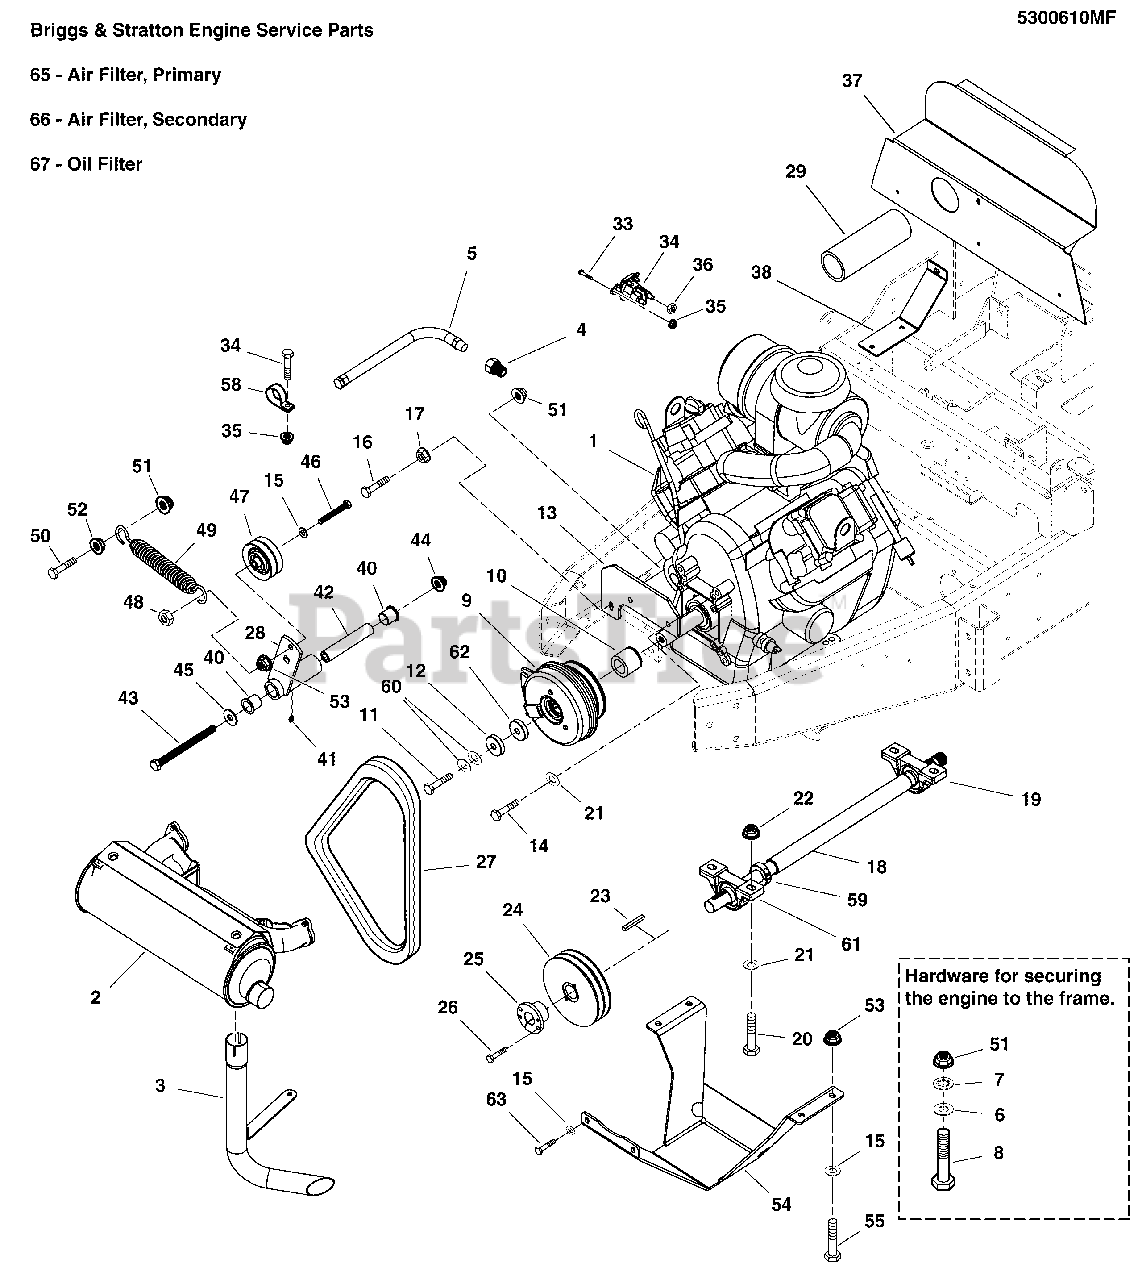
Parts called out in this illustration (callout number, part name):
1	ENGINE, HORIZONTAL, B&S
2	MUFFLER, VANGUARD
3	TAIL PIPE, VANGUARD
4	METRIC ADAPTER, M14-1.5" TO 3/8 NPTF
5	HOSE, OIL DRAIN
6	WASHER, 5/16
7	WASHER, 5/16" Internal Tooth Lock
8	BOLT, 5/16-18 X 2-1/4" GD5 YZ
9	CLUTCH, WARNER, OUT-FRONT
10	SPACER, 1.13 X 1.75 X .90, YZ
11	BOLT, CRANKSHAFT, 7/16 X 1-3/4
12	SPACER, .45 X 1.88 X .38
13	PLATE, CLUTCH ANCHOR - RED
14	BOLT, 7/16-14 X 1 GD5
15	WASHER, Flat, 3/8
16	BOLT, 5/16-18 X 3-3/4 GD5
17	NUT, 5/16-18 HEX SERRATED FLANGE (LARGE)
18	SHAFT, PUMP DRIVE, S800X
19	BEARING, PILLOW BLOCK, 1
20	BOLT, 7/16-20 X 1-3/4 GD5
21	WASHER, 7/16 GD9 YZ
22	NUT, 7/16-20 HEX NYLON LOCK
23	KEY, 1/4" SQ. X 2.00
24	PULLEY, 6.45" OD, DOUBLE A
25	BUSHING, TAPERED HUB
26	BOLT, 1/4-20 X 1", GD
27	BELT, A-SEC, 37.08 EL, ARAMID, RAW EDGE
28	WELD, IDLER ARM - RED
29	HOSE, AIR INLET, 2 ID X 7 LONG
33	SOLENOID-4 POLE 12 VOLT DC (TROMBETTA)
34	CAPSCREW, Hex Head, 1/4-20 x 3/4 (stiffener to top of cover)
35	NUT, Serrated Flange, 1/4-20
36	NUT, Hex, 5/16-24
37	PLATE, HOOD BAFFLE, B&S 31 - RED
38	BRACKET, BAFFLE SUPPORT - RED
40	BUSHING, FLANGE, 7/8 X 1 L
41	GREASE FITTING, 1/4-28 STRAIGHT
42	SLEEVE, A-ARM PIVOT-LONG
43	BOLT, 1/2-13 X 6 GD5 YZ
44	NUT, Hex Flange, 1/2-13
45	WASHER, 1/2" USS
46	CAPSCREW, Hex Head, 3/8-16 X 2-3/4
47	PULLEY, IDLER DOUBLE-A
48	NUT, Hex, Side Lock, 3/8-16
49	SPRING-EXT, 1.25 ODX5.70LGX.142WR, BLK
50	CAPSCREW, Hex Head, 5/16-18 X 1-1/4
51	NUT, Ny Lock Flange, 5/16-18
52	NUT, 5/16-18, Hex Serrated Flange (Small)
53	NUT, 3/8-16, Hex Flange Nylock
54	PLATE, SKID - RED
55	CAPSCREW, Hex Head, 3/8-16 x 1-1/4
58	CLAMP, VINYL INSULATED, 1.00
59	COLLAR, Split, 1"
60	BELLEVILLE, WASHER, 1.1875 X .442 X .089
61	BEARING, 1" GRIP-IT, PILLOW BLOCK
62	SPACER, 1.13 X 1.5 X .41, YZ
63	CAPSCREW, Hex Head, 3/8-16 x 1
65	Filter-Air Cleaner Cartridge
66	Filter-Air Cleaner Cartridge
67	Filter-Oil
